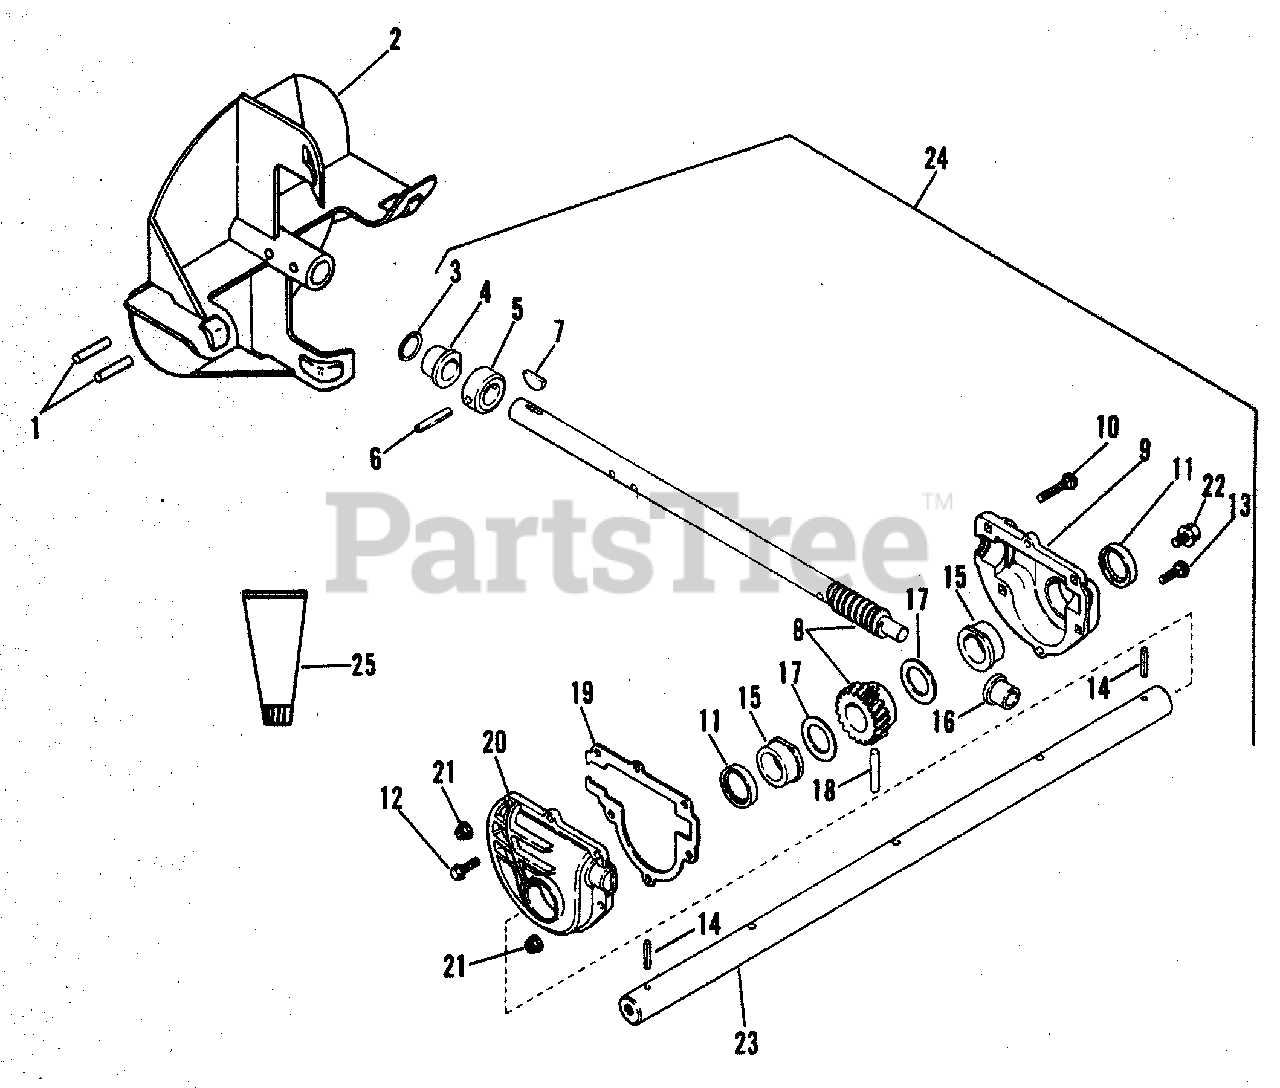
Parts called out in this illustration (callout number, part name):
1	PIN-ROLL .250X1.75
2	FAN - 12"
3	O-RING .250X.943X.103
4	BSHG-FLG .750X1.000X.750X1.250
5	THRUST COLLAR
6	PIN-GRV .188X1.25 TP A
7	KEY-WDRF .188X.875X.375 SAE11
8	WORM SHAFT & GEAR ASSY
9	GEAR CASE HALF L H
10	BLT-RDHDSQNK .25-20X1.25 GR5PL
11	SEAL 1.000X1.312X.150
12	SCR-TAP 10-24X.75 HWH PL TR
13	BLT-RDHDSQNK .25-20X.88 PL
14	PIN-ROLL .188X1.50
15	BSHG-FLG1.000X1.12X.62X1.50BR
16	BSHG-FLG .500X.750X.750X1.000
17	WSHR-HRD-THRS 1.007X1.542X.062
18	PIN-GRV .313X1.44 TP C
20	GEAR CASE HALF R H
21	NUT-SPNLK-FLG .25-20 YWZC
22	SCR-TAP .375-16X .50 HWH PL TR
23	SHAFT, RAKE - 24"
24	GEAR CASE - 24" - ALUMINUM
24	Requires 2 Oz. Liquid Grease
25	8 OZ TUBE OF LIQUID GREASE
